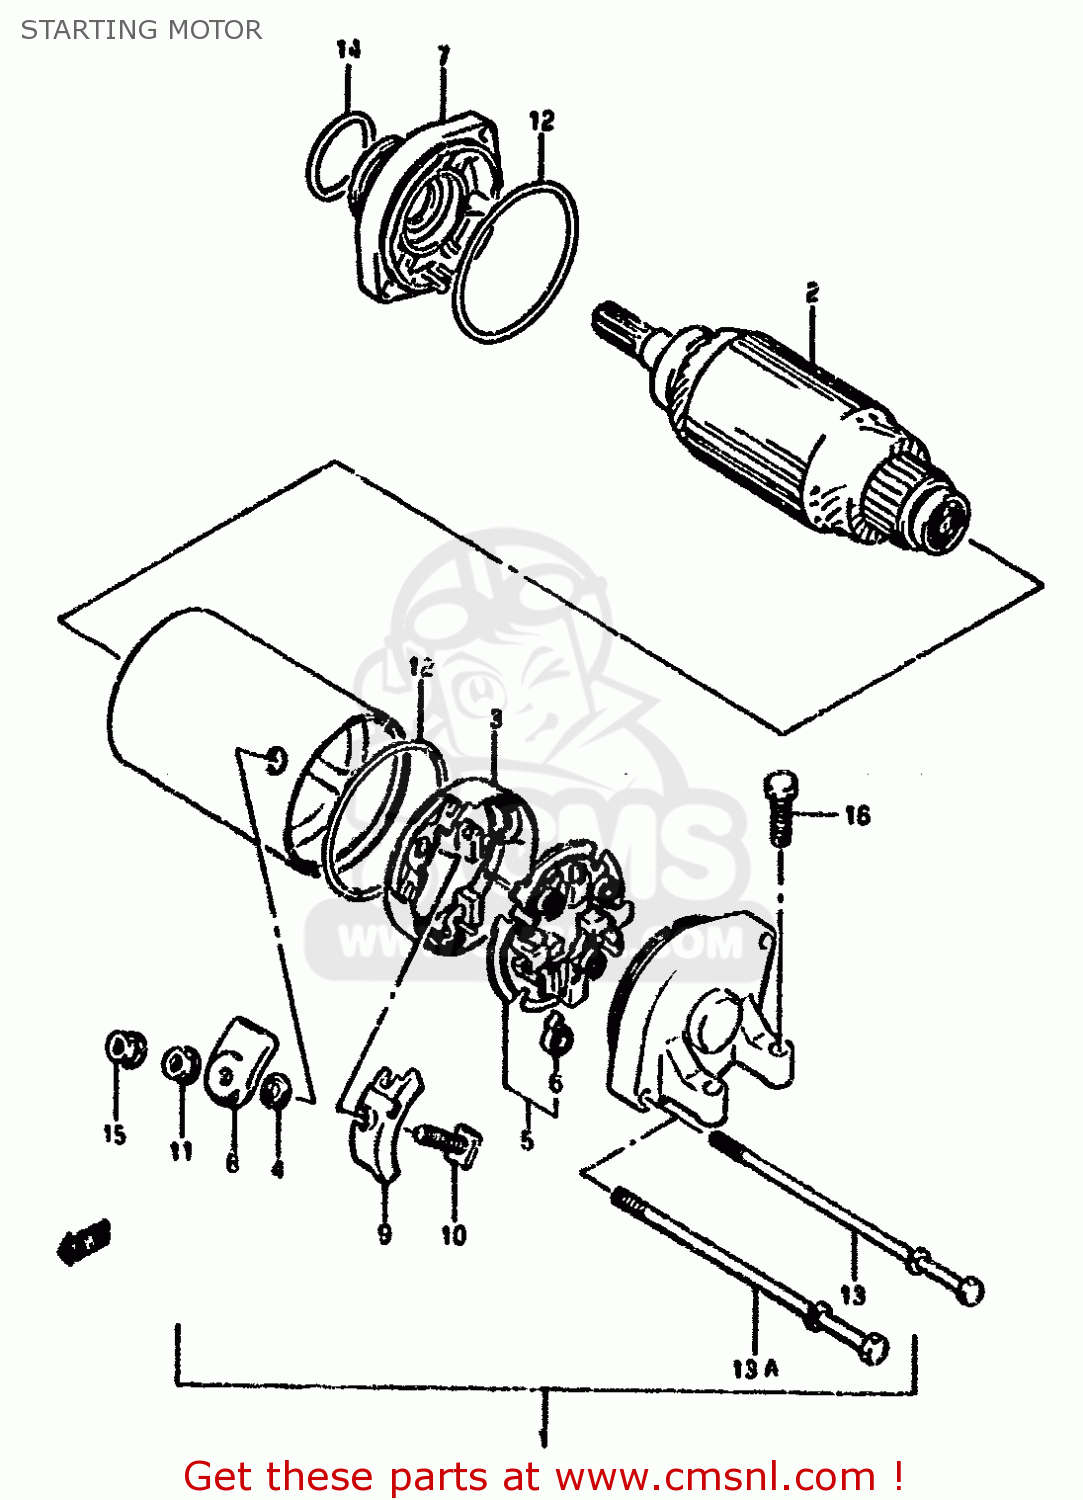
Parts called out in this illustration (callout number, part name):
1	MOTOR ASSEMBLY,STARTING
2	ARMATURE
3	TERMINAL SET,BRUSH
4	GASKET (NAS)
5	HOLDER SET,BRUSH(-)
6	SPRING
7	BRACKET SET
8	BUSHING
9	BUSHING
10	BOLT
11	NUT
12	O RING
13	BOLT,STARTING
13A	BOLT,STARTING MOTOR
14	O RING
15	NUT
16	SCREW (6X25)
